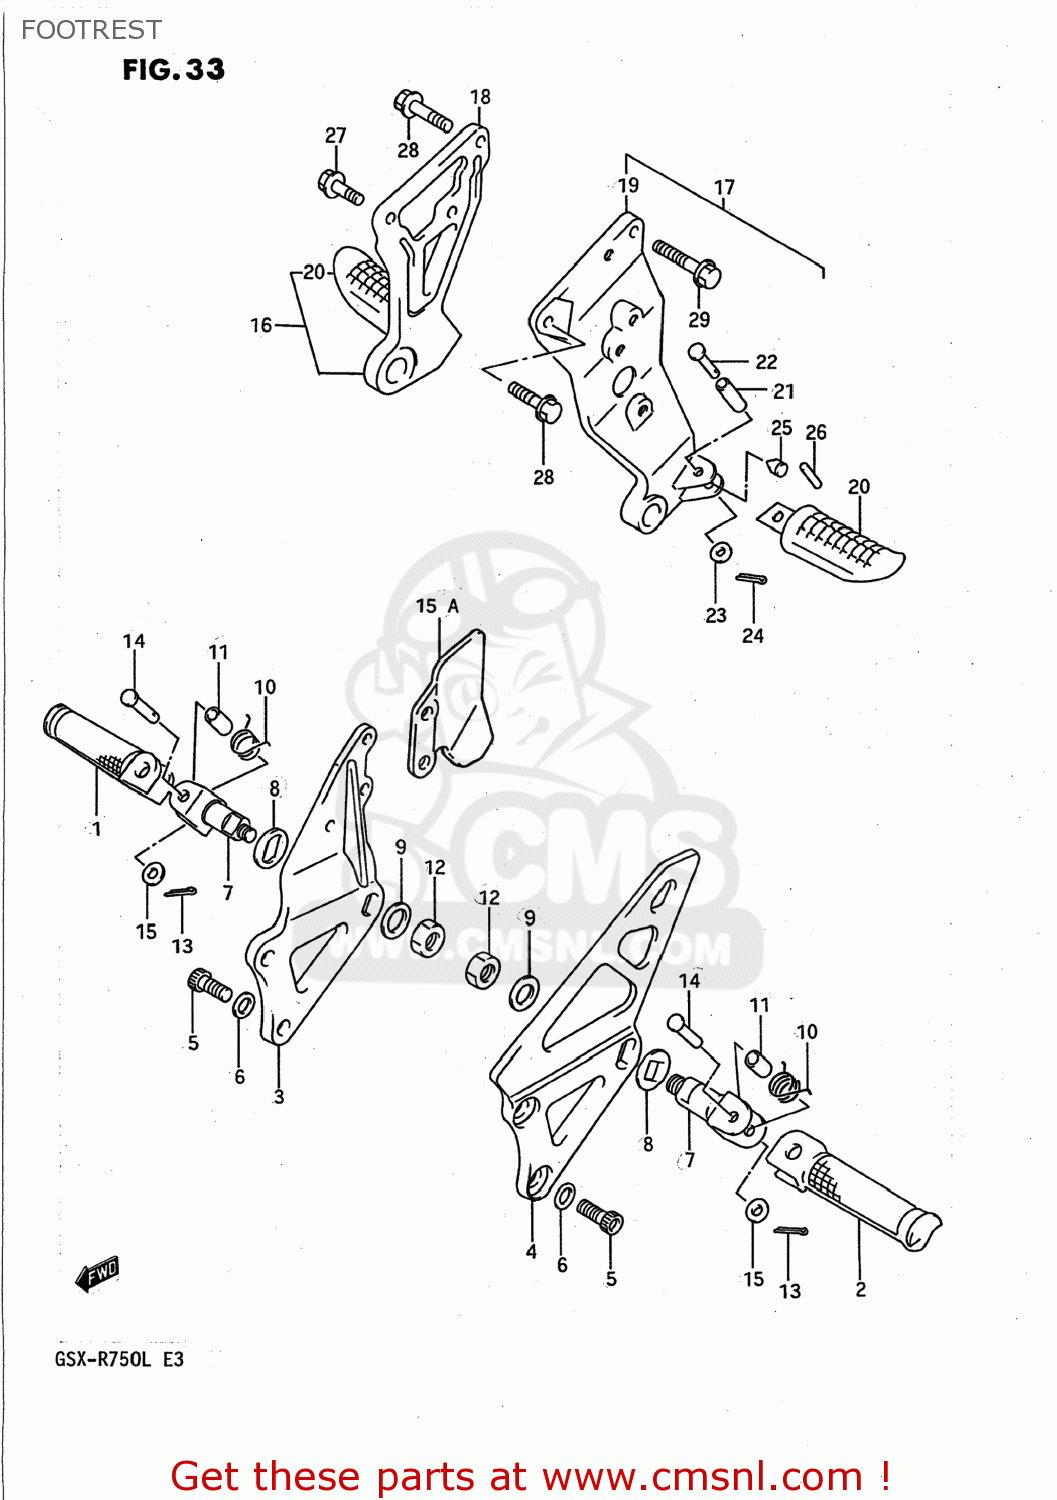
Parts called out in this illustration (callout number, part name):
1	BAR,FOOTREST,R
2	BAR,FOOTREST,L
3	BRACKET,FRONT FOOTREST
4	BRACKET,FOOTREST,LEFT
5	BOLT,FOOTREST BRACKET
6	WASHER
7	BOSS,FOOTREST
8	PLATE,FOOTREST INNER
9	WASHER,FR FOOTREST
10	SPRING
11	SPACER(8.1X12X22)
12	NUT 12MM
13	PIN 20X15
14	PIN
15	WASHER
15A	GUARD,FRONT FOOTREST,RIGHT
16	FOOTREST ASSEMBLY,PILLION
17	FOOTREST ASSY,PILLION,L
18	BRACKET,PILLION FOOTREST
19	BRACKET
20	BAR,PILLION FOOTREST R
21	SPACER(8.1X12X22)
22	PIN
23	WASHER
24	PIN 20X20
25	CUSHION,FOOTREST HOLDER
26	PIN (4X20.8)
27	BOLT
28	BOLT
29	BOLT
